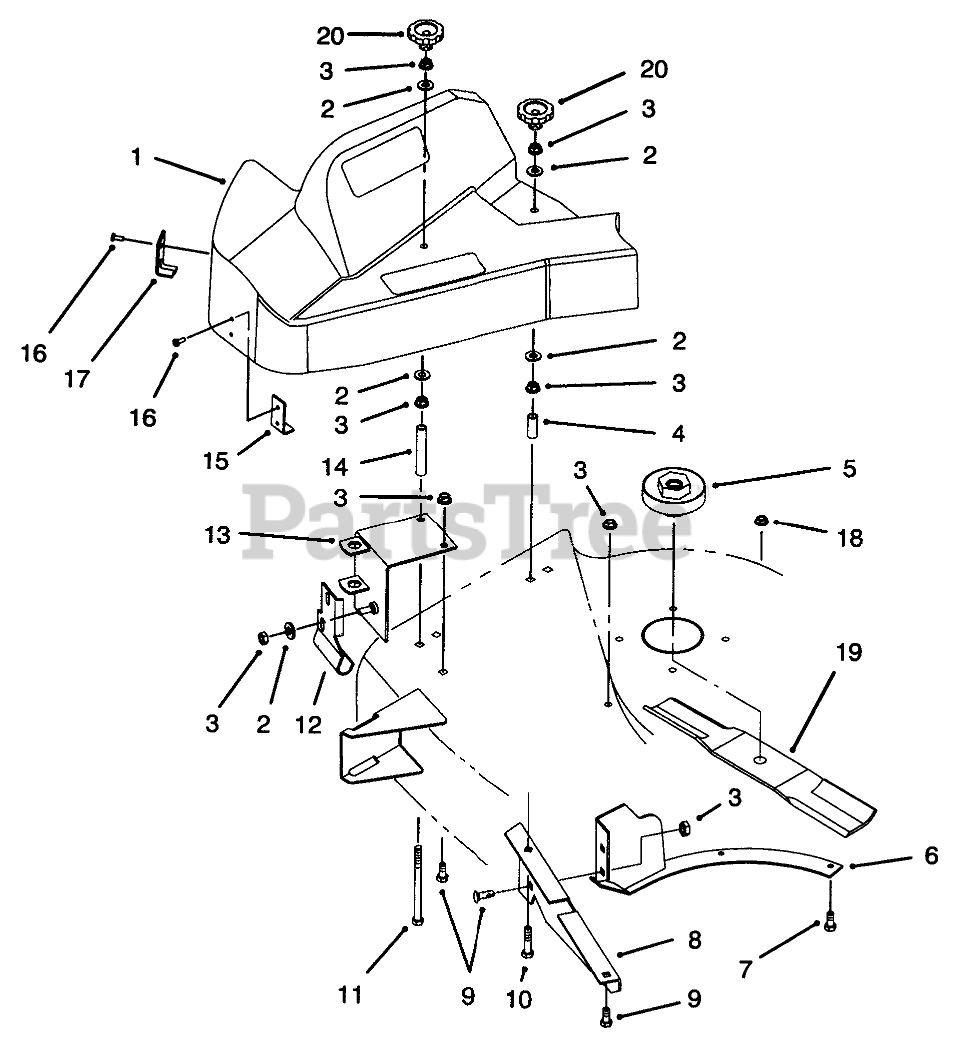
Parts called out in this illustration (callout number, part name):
1	Shield-Belt (Incl. Ref. #15-17)
2	WASHER-PLAIN
3	NUT-LOCK, NI
4	TUBE-LATCH
5	PULLEY
6	BAGGING RING RH-WELDED B
7	SCREW-HH
8	Baffle-Rear
9	SCREW-CARR
10	SCREW-CARR
11	SCREW-CARR
12	BRACKET - PIVOT BLACK
13	WA - PIVOT BRACKET
14	TUBE-SPACER
15	BRACKET-SUPPORT, SHIELD
16	RIVET-POP
17	BRACKET-SUPPORT, SHIELD
18	NUT-LOCK, NI
19	Blade
